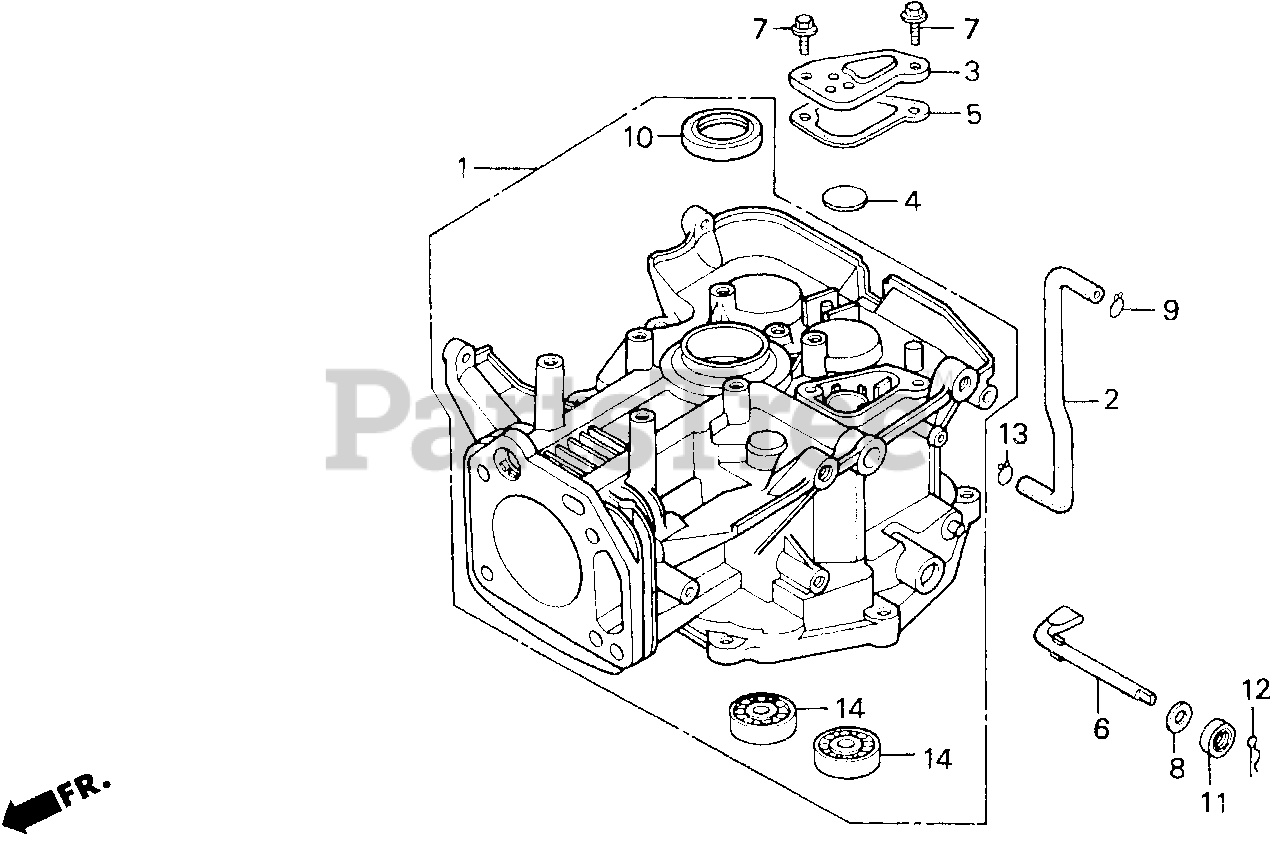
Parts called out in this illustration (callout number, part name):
1	CYLINDER ASSY.
2	TUBE, BREATHER
3	CAP, BREATHER CHAMBER
4	VALVE, BREATHER
5	GASKET, BREATHER CAP
6	SHAFT, GOVERNOR ARM
7	BOLT, FLANGE (6X12) (CT200)
8	WASHER, THRUST (8.1MM)
9	CLIP, TUBE
10	OIL SEAL (35X52X8)
11	OIL SEAL (8X14X5)
12	PIN, LOCK (8MM)
12	PIN, LOCK (10MM)
13	CLIP, TUBE (C11)
14	BEARING, RADIAL BALL (6202)
